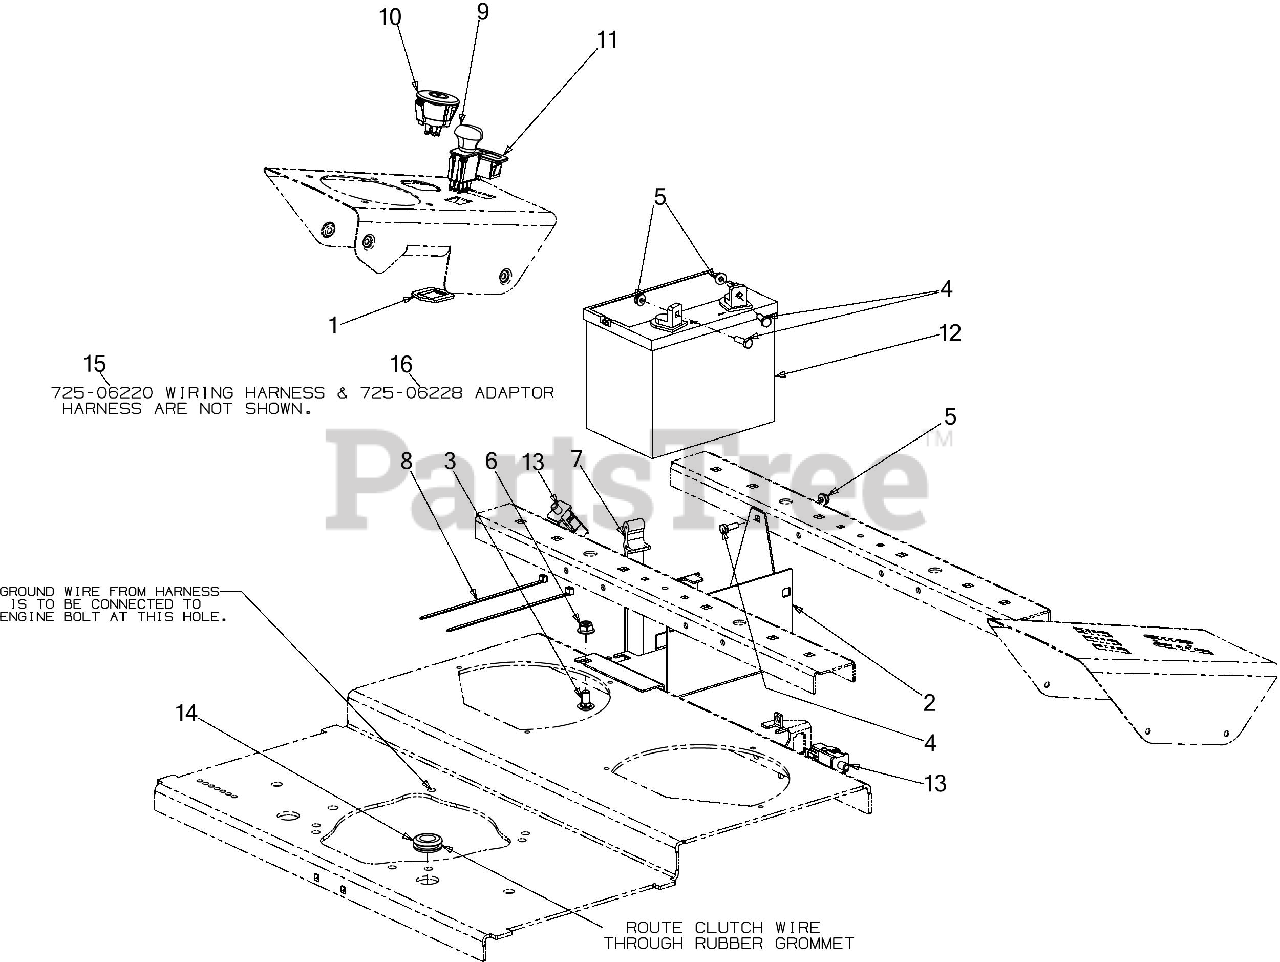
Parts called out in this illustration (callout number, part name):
1	PTO SWITCH BRACKET
2	BATTERY BRACKET
3	CARRIAGE BOLT 3/8-16 x .750 GR5
4	SCREW 1/4-20X.75 GR5
5	FLANGE LOCK NUT
7	BATTERY RETAINER STRAP
8	7" CABLE TIE
9	ELECTRIC PTO SWITCH
10	KEY SWITCH 3 POSITION
11	HOUR METER
13	PLUNGER SWITCH
14	RUBBER GROMMET
